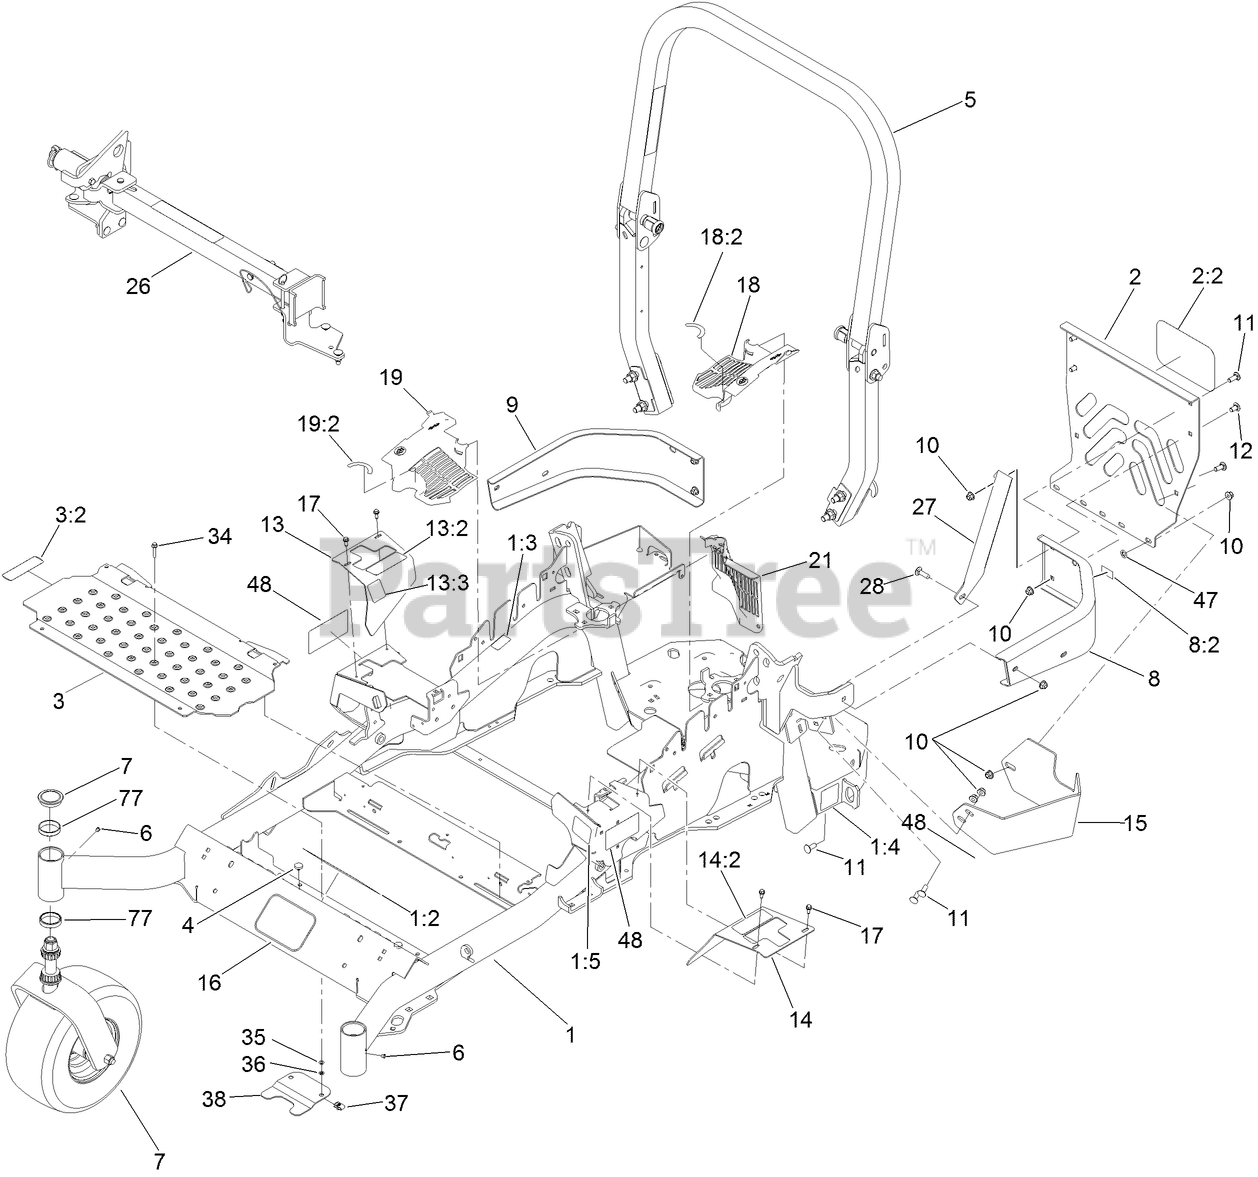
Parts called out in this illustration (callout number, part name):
1	MAIN FRAME ASM
1:2	DECAL-WARNING, SLOPE
1:3	DECAL-WARNING
1:4	DECAL-HAZARD, PINCHED FINGER
1:5	DECAL-FUEL FILL, CE
2	REAR GUARD ASM
2:2	DECAL
3	FLOORPAN ASM
3:2	DECAL-MISSING, COVER
4	BUMPER
5	ROPS ASM
7	Caster Wheel ASM
8	LH REAR BUMPER ASM
8:2	DECAL-WARNING
9	BUMPER-RH
10	NUT-HF, NI
11	SCREW-CARR
12	SCREW-CARR
13	RH MOTION CONTROL COVER ASM
13:2	DECAL-CONTROL, MOTION
13:3	DECAL-PARK BRAKE, CE
14	LH MOTION CONTROL COVER ASM
14:2	DECAL-CONTROL, MOTION
15	GUARD-MUFFLER
16	DECAL
17	SCREW-HWH
18	LH HYDRO GUARD ASM
18:2	DECAL-HYDRO OIL
19	RH HYDRO GUARD ASM
19:2	DECAL-HYDRO OIL
21	GUARD-HYDRO, REAR (RH)
26	Z STAND ASM
28	BOLT-CARR
34	SCREW-HHF
35	WASHER-FLAT
36	NUT-RETAINER
38	ADAPTER-CAPTIVE
47	NUT-PUSH
77	CUP-BEARING
